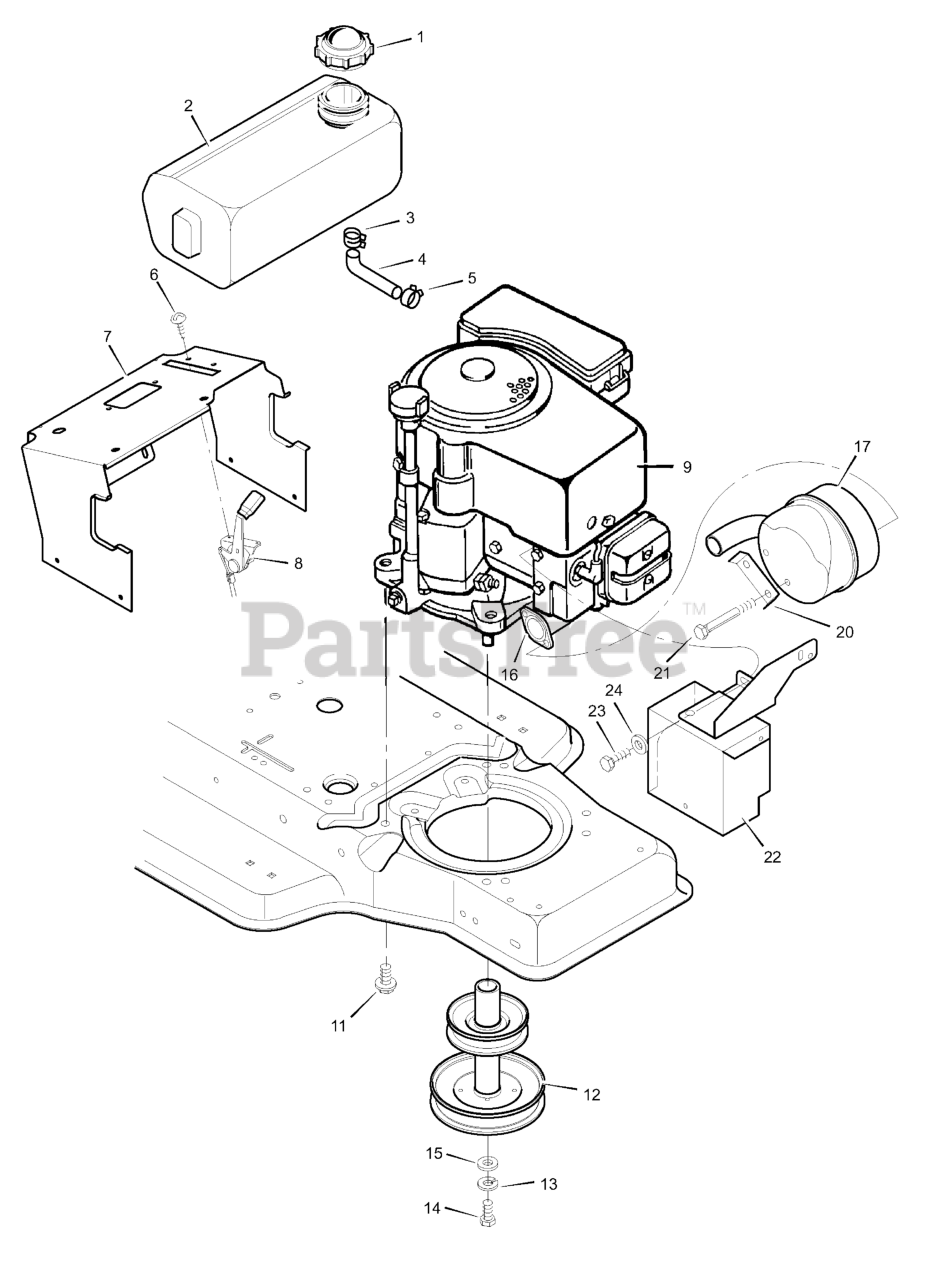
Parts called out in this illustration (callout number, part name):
1	Fuel Cap
2	Fuel Tank
3	Hose Clamp
4	Fuel Line
5	Hose Clamp
7	Support, Dash
8	Throttle Control
9	Engine *
11	Bolt, Engine Mount
12	Stack Pulley Assembly
13	Lockwasher
14	Bolt, Hex
16	GASKET, Exhaust
17	Muffler
20	Lock, Screw
22	Shield, Heat
